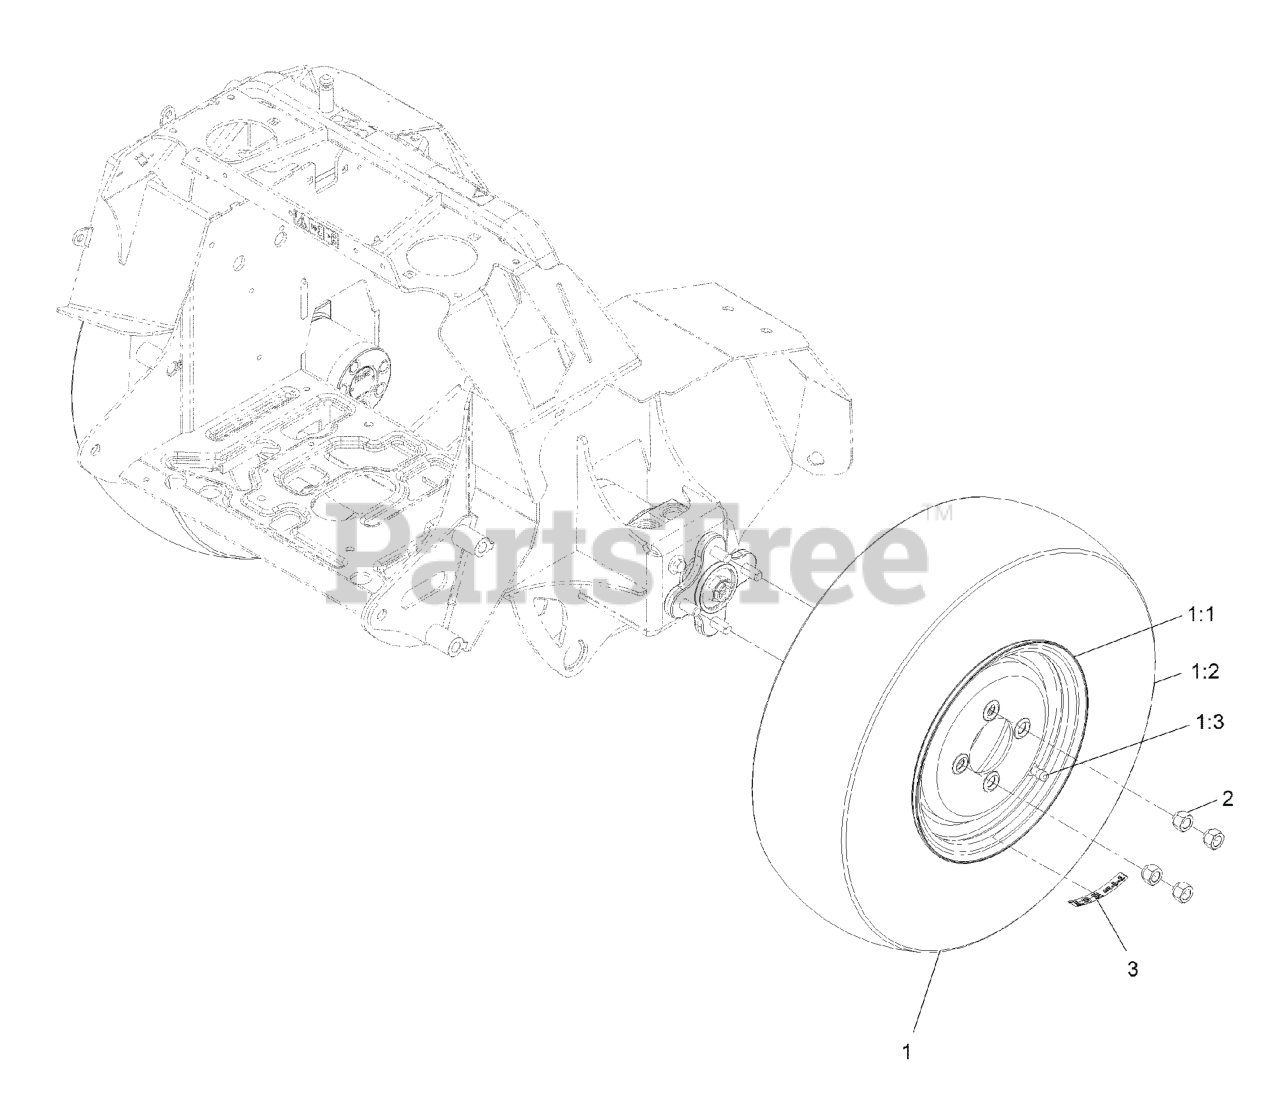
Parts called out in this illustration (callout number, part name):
1	ASM-WHL TIRE
1:1	WHEEL 10 X 5.5 WHT
1:2	TIRE 21X7.00-10
1:3	Stem-Valve
2	NUT-LUG
3	DECAL-TORQUE WHEEL LUG-HU
